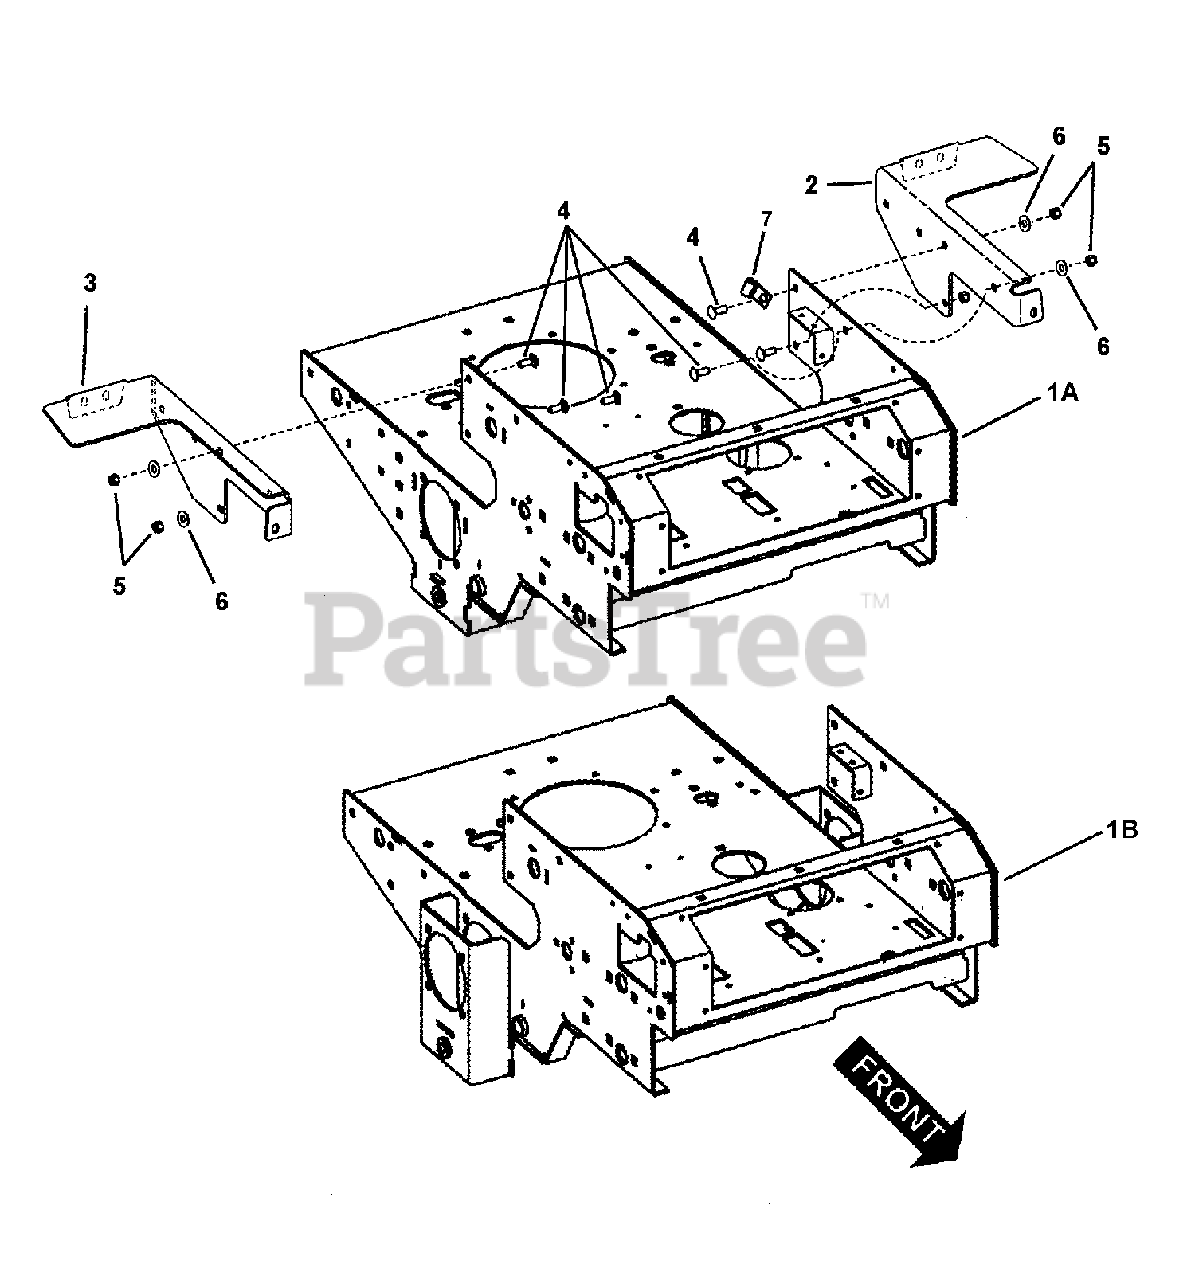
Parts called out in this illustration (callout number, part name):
1A	WELDMENT, Rear Frame
1B	WELDMENT, Rear Frame
2	WELDMENT, L.H. Tank Bracket
3	WELDMENT, R.H. Tank Bracket
4	BOLT, 3/8-16 x 1" Square Neck Carriage, GR 5
5	NUT, 3/8-16 HEX NYLON LOCK
6	WASHER, 3/8" SAE Flat
7	CLIP, Open 3/8" Cushioned
